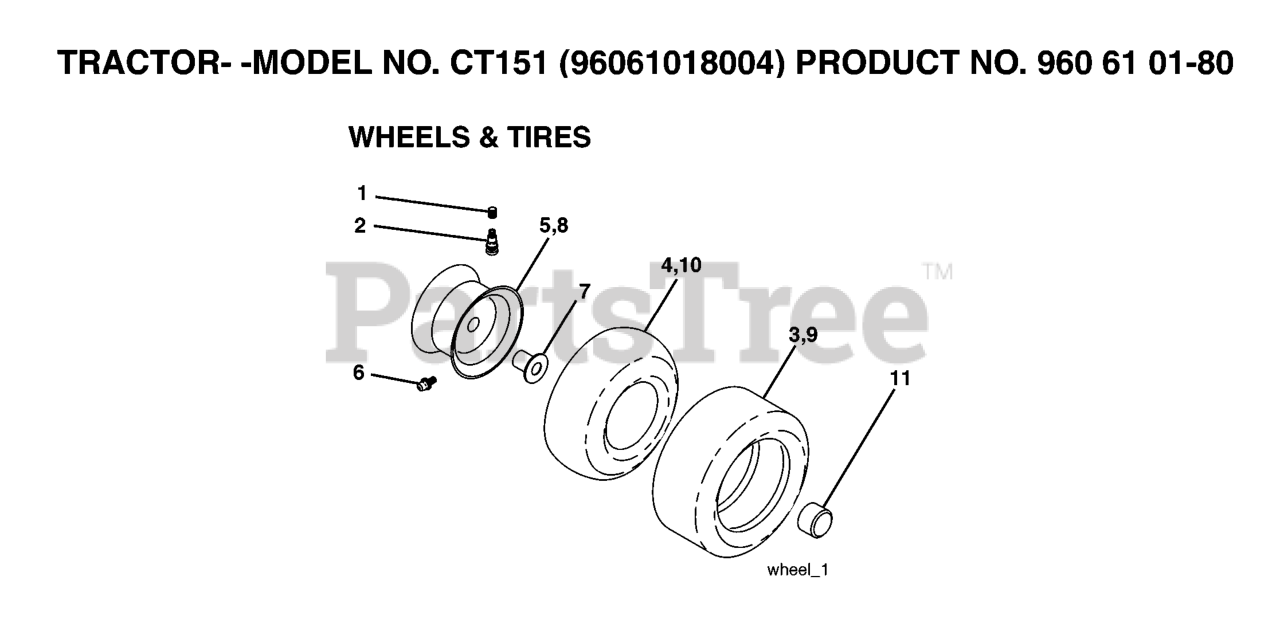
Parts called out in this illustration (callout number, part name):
2	VALVE STEM LT
3	TIRE HEAVY DUTY
4	TUBE.5.3/4.5/6
5	RIM ASM 6" FRONT SILVER
6	FITTING LT
7	BEARING T
8	RIM ASM 8" REAR SILVER
9	TIRE HEAVY DUTY
10	TUBE
11	CAP, AXLE BLK
